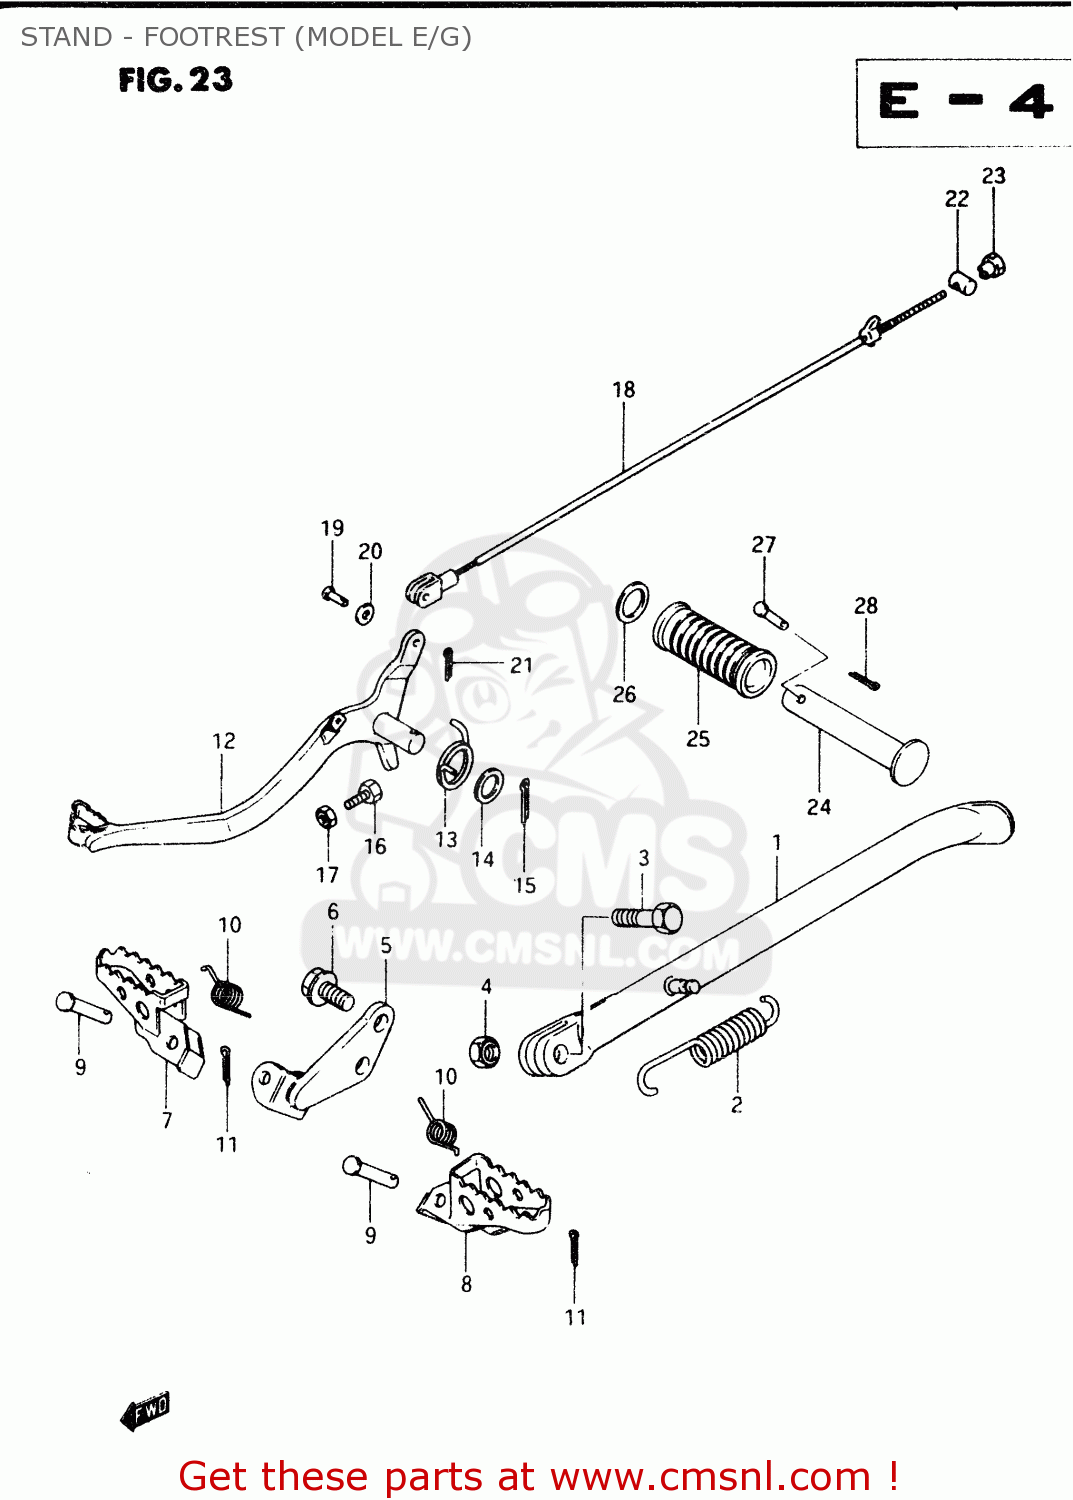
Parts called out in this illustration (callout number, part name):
1	STAND,SIDE
2	SPRING
3	BOLT L:30
4	NUT
5	HOLDER, FOOTREST RH (BLUE)
6	BOLT
7	FOOTREST, FRONT RH (BLUE)
8	FOOTREST,FR.L.
9	PIN
10	SPRING
11	PIN 25X20
12	PEDAL,BRAKE
13	SPRING
14	WASHER(15.5X26X2.3)
15	COTTER PIN
16	BOLT
17	NUT
18	CABLE,RR BRAKE
19	PIN(L:17.5)
20	WASHER
21	PIN 20X20
22	PIN(11X18)
23	NUT (6MM)
24	BAR,FOOTREST RUBBER
25	RUBBER,PILLION FOOTREST
26	WASHER (19.5X32X2)
27	PIN
28	PIN 20X20
